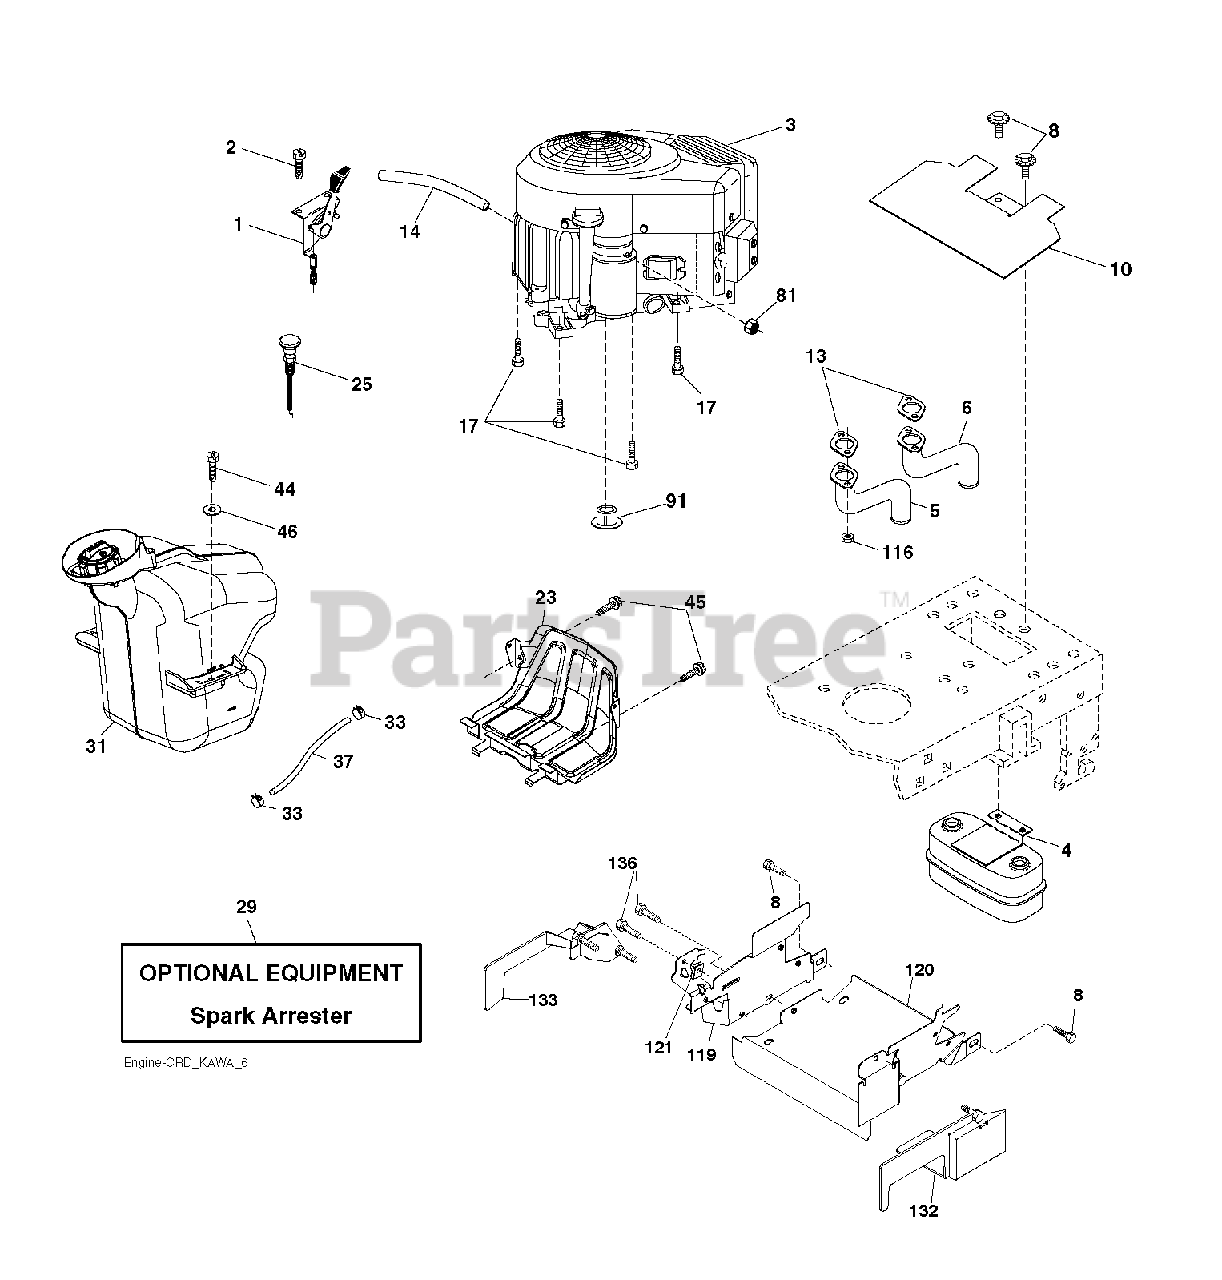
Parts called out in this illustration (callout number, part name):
1	THROTTLE CABLE
2	SCREW.#10 X 0.750.BOS
4	MUFFLER.TWIN.CYL.LOW.TONE
5	TUBE.EXHAUST.LH.FR961/FR730
6	TUBE.EXHAUST.RH.FR961/FR730
8	BOLT, 5/16-18 X 1 3/4
10	SHIELD.HEAT.MUFFLER
14	TUBE, DRAIN OIL ASM.
17	SCREW 3/8-16X1
23	SHIELD.BROWNING.PNT.GT.V2
25	CONTROL.CHOKE.ERGO.PUSH-IN.BLA
29	KIT.SPARK ARRESTOR 794945 B&S
33	HOSE CLAMP
37	LINE.FUEL.20
44	SCREW HEXWSHR 1/4-20X3/4
45	SCREW, 3/8-16X3/4
81	NUT
91	BUSHING.1.375OD
116	NUT.HEX.FLANGE.TOPLOCK
119	LENKRAD
120	GUARD 532199767
132	SHIELD RIGHT
133	SHIELD LEFT
136	SCREW.1/4-20X5/8
